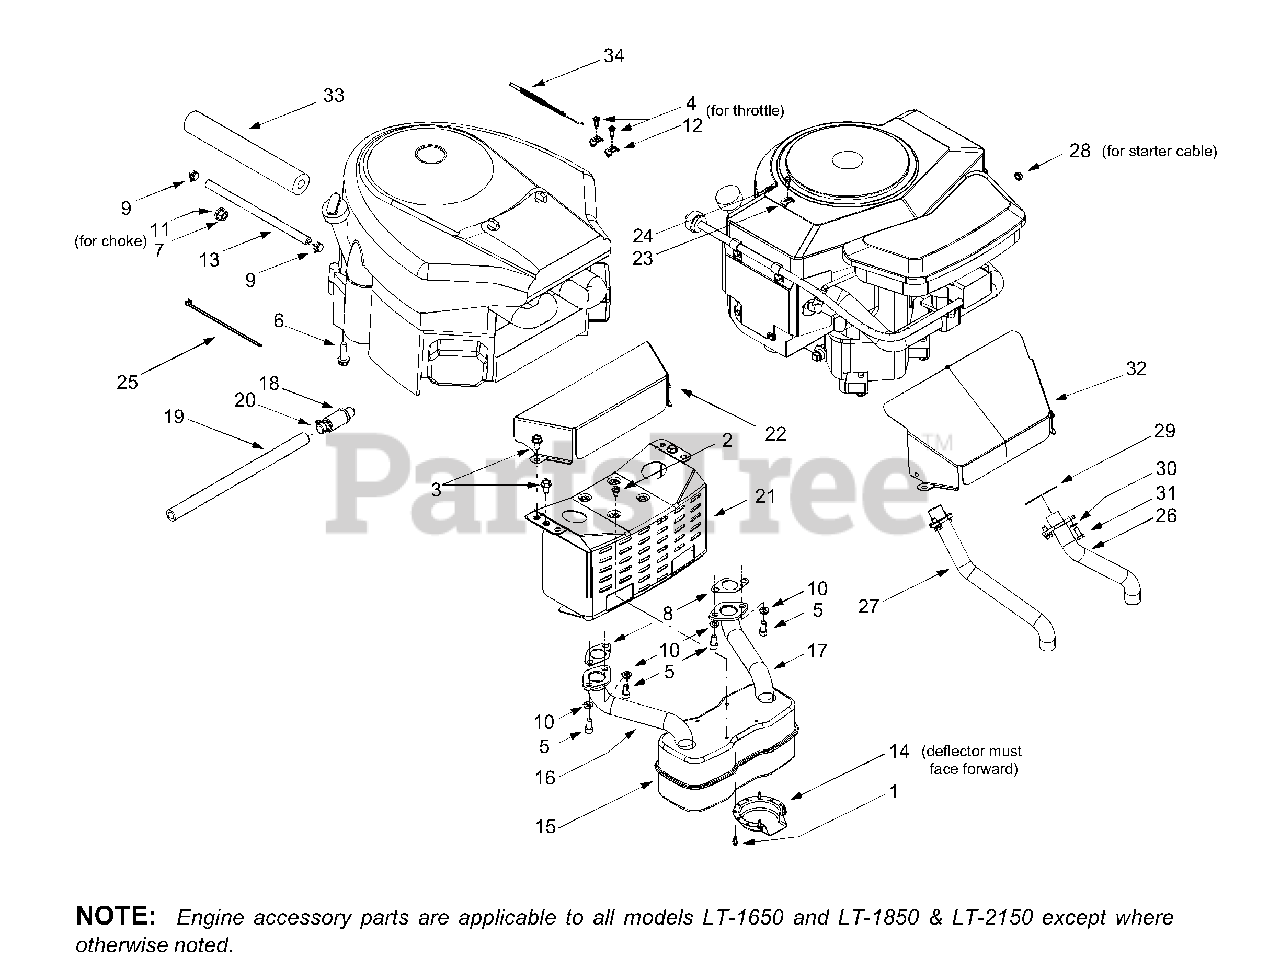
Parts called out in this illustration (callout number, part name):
1	Self-tapping Screw, #8-32 x .375
2	Self-tapping Screw, 1/4-20 x .5
3	Self-tapping Screw, 5/16-18 x .625
4	Screw, #10-32 x .625
5	Socket Cap Screw, 5/16-18 x .625
6	Self-tapping Screw, 3/8-16 x 1.25
7	Hex Nut, 3/8-16
8	Exhaust Gasket (Models LT-1850/2150)
9	Hose Clamp
10	Lock Washer, 5/16
11	Lock Washer, .406 x .875 x .059
12	Casing Clamp (Models LT-1850/2150)
13	Fuel Line Hose
14	Muffler Deflector
15	Muffler, Twin Inlet
16	RH Exhaust Pipe (Models LT-1850/2150)
17	LH Exhaust Pipe (Models LT-1850/2150)
18	Oil Drain Valve
19	Oil Drain Hose
20	Oil Drain Cap
21	Muffler Heat Shield
22	Engine Heat Shield (Models LT-1850/2150)
23	Clamp, 9/16 (Model LT-1650)
24	Screw, #10-16 x .5 (Model LT-1650)
25	Cable Tie
26	LH Exhaust Pipe (Model LT-1650)
27	RH Exhaust Pipe (Model LT-1650)
28	Hex Sems Nut, 1/4-20 (Model LT-1650)
29	Exhaust Gasket (Model LT-1650)
30	Lock Washer, 1/4 (Model LT-1650)
31	SCREW 1/4-20 x .620 GR5
32	Heat Shield (Model LT-1650)
33	Foam, .625 x 1.5 x 10 (fits over fuel line)
34	THROTTLE CABLE
34	Choke Cable
